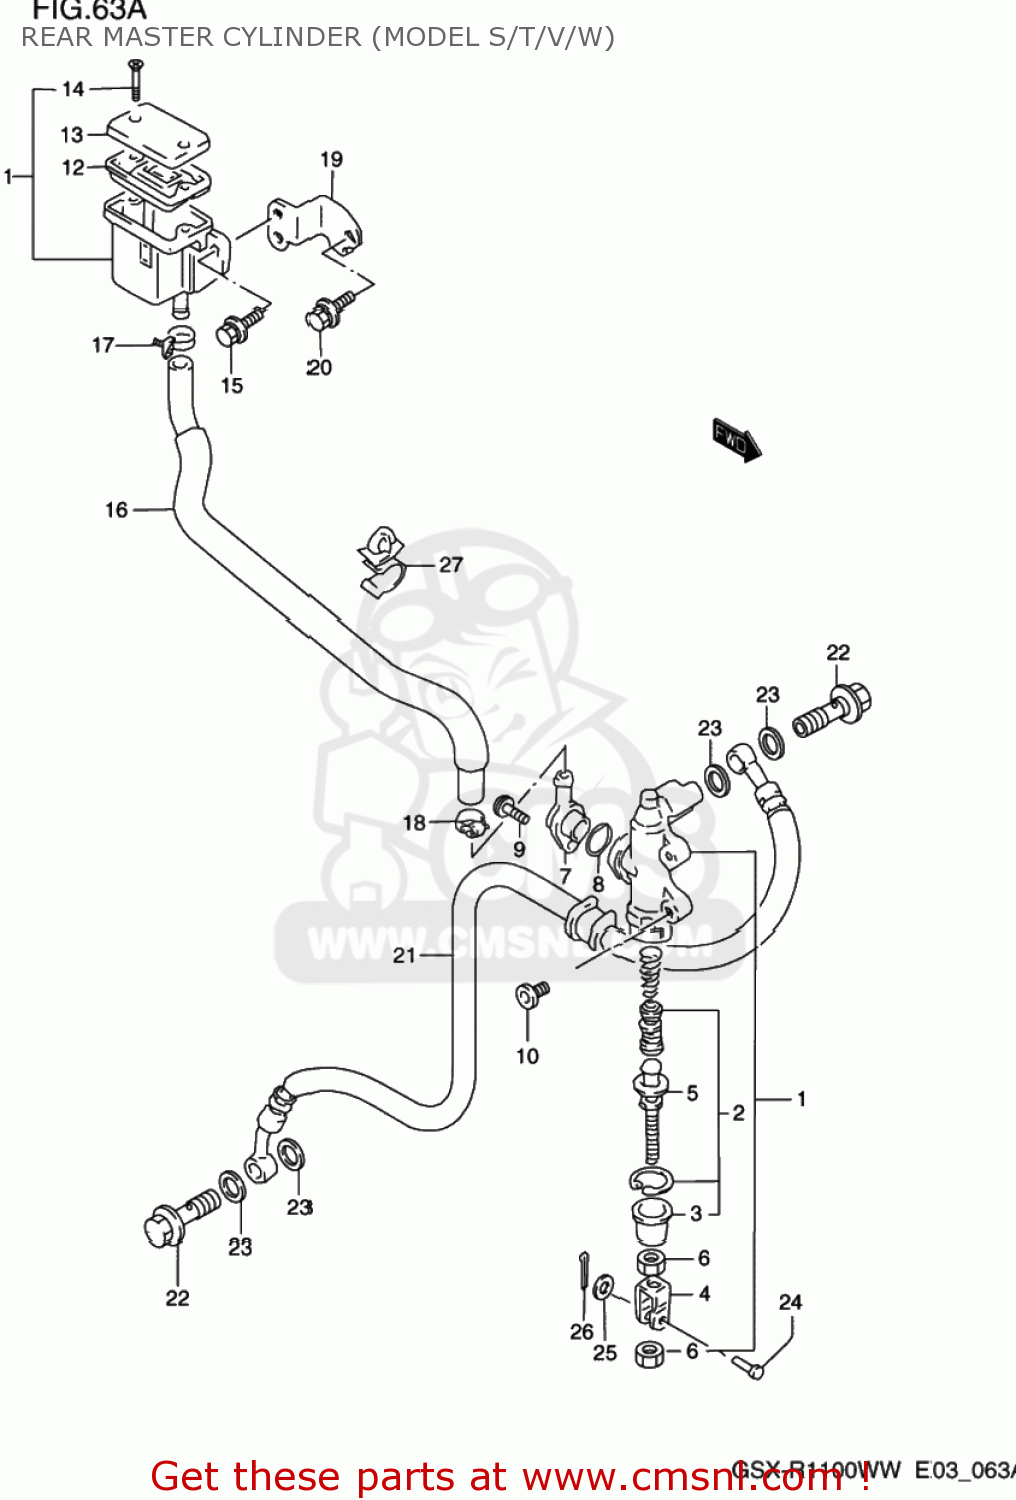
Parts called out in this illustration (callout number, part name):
1	CYLINDER ASSEMBLY,REAR MASTER
2	PISTON/CUP SET
3	BOOT
4	YOKE
5	ROD,PUSH
6	NUT
7	CONNECTOR
8	O RING
9	SCREW
10	BOLT 8X20
11	TANK ASSY,RESERVOIR
12	DIAPHRAGM
13	CAP
14	SCREW
15	BOLT
16	HOSE,RESERVOIR TANK
17	CLIP
18	CLIP
19	PLATE,RESERVOIR TANK
20	BOLT
21	HOSE,RR BRAKE
22	BOLT UNION
23	WASHER(10X15X1.5)
24	PIN
25	WASHER
26	PIN
27	CLAMP
